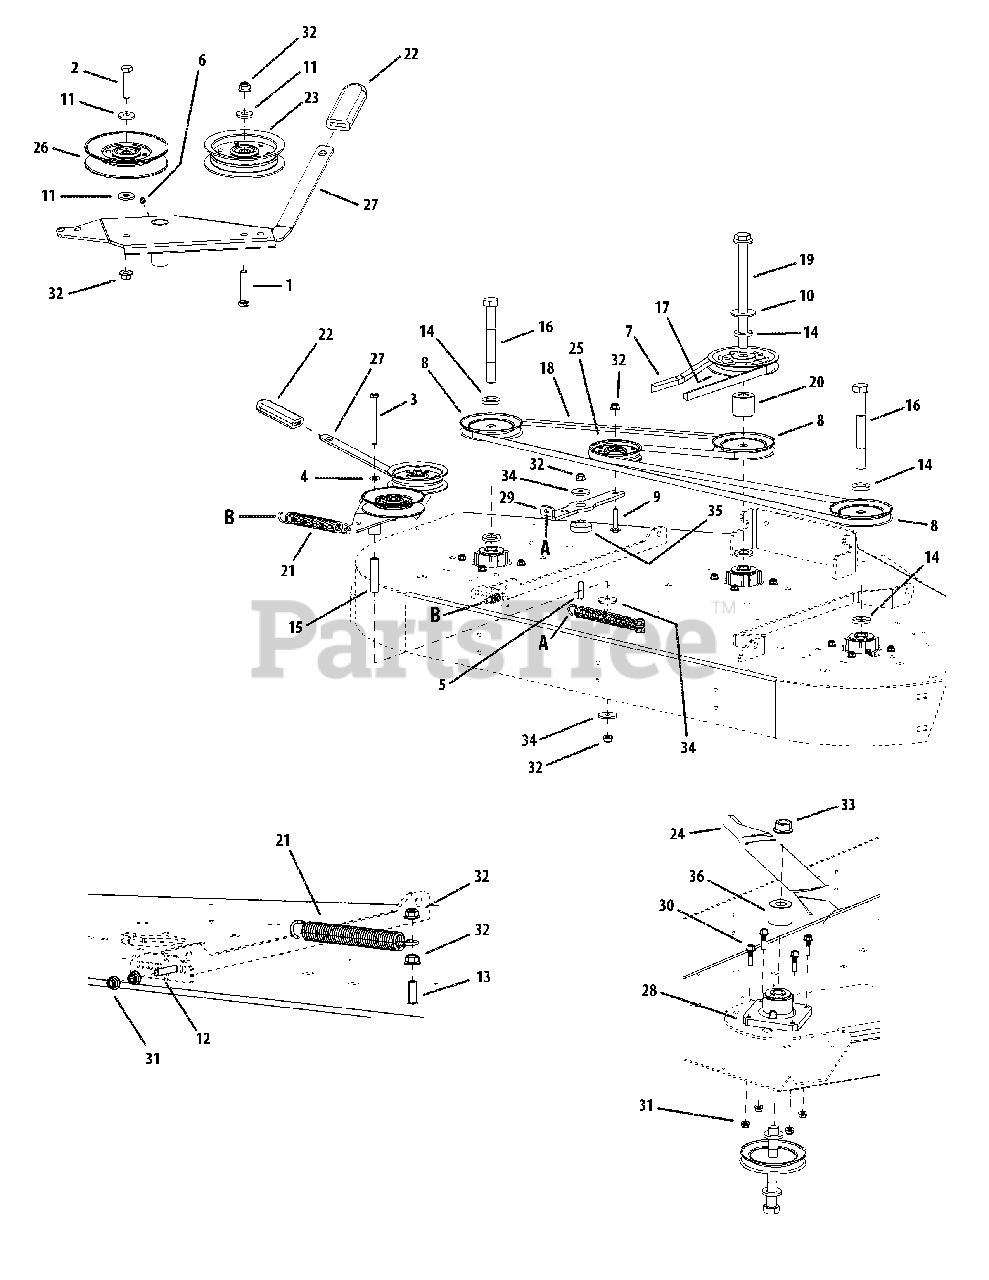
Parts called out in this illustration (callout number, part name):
1	Hex Cap Screw, 3/8-16 x 2.00
2	Hex Cap Screw, 3/8-16 x 1-3/4
3	Hex Cap Screw, 3/8-16 x 4.00
4	Washer, 3/8
5	Carriage Bolt, 3/8-16 x 1-1/2
6	Grease Fitting, 1/4-28 x 3/16
7	V-Belt, B-Section, BK90, PTO
8	V-Pulley, 4.90 OD
9	Carriage Bolt, 3/8-16, 1.75
10	Flat Washer, .781 ID 2.00 OD, .105
11	Flat Washer, .406 ID, 1.0 OD, .105
12	Carriage Bolt, 5/16-18 x 1.75
13	Carriage Bolt, 3/8-16 x 1.25
14	Spacer, .812 ID x 1.47 OD x .218
15	Spacer, .39 x .635 x 2.75
16	Hex Cap Screw, 3/4-16 x 6.50
17	V-Pulley, 5.774 OD
18	V-Belt, A Section x 122.3, Deck
19	Hex Cap Screw, 3/4-16, 9.00
20	Spacer, .76 ID x 1.75 OD x 1.60
21	Extension Spring, .94 x OD x 7.57
22	Grip, 1.0 x 3.2 x .25
23	Idler Pulley, 4.06 OD
24	Hi-Lift Blade, 21.0, 0.756 ID
25	Flat Pulley with Flanges
26	Idler Pulley, 5.06 OD
27	Idler Arm Assembly includes:
27	Bearing
28	Aluminum Spindle Assembly
30	Bolt, 5/16-18 x 1.25
31	Nut, 5/16-18, Nylon Flange Lock
32	Nut, 3/8-16, Nylon Flange Lock
33	Flange Hex Nut, 3/4-16
34	Washer, .390 x 1.500 x .134
35	Shoulder Screw, .854 x .280
36	Spacer, .76 ID x 1.75 OD x 1.50
